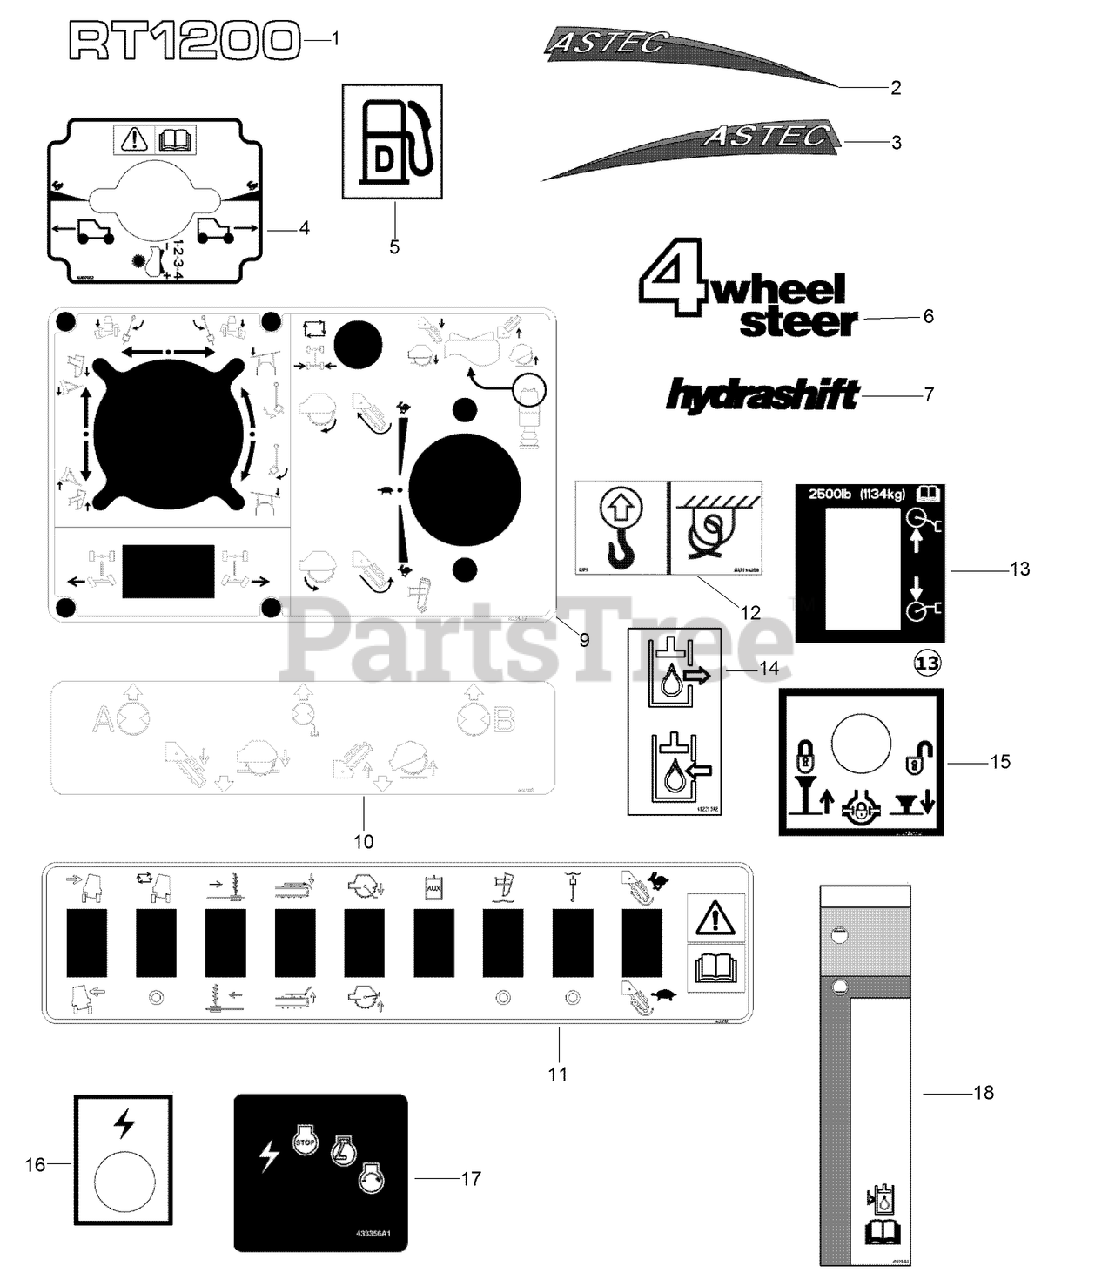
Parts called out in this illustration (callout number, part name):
1	DECAL - RT1200 Model
2	DECAL - Astec Swoosh, Right Hand
3	DECAL - Astec Swoosh, Left Hand
4	DECAL - Ground Drive Joystick
5	DECAL-Diesel Fuel
6	DECAL-4 Wheel Steering
7	DECAL - Hydrashift Model Name
9	DECAL - Op Rhs Joystick
10	DECAL - Rear Bulkhead ID
11	DECAL - Rear Switches Overlay
12	DECAL-Tie Down / Lift Hook
13	DECAL - Instrument Panel, LH
14	DECAL-Hydraulic Oil, Supply / Return
15	DECAL-Instrument Panel, RH
16	DECAL-Instrument Panel, RH
17	DECAL-Key Switch
18	DECAL-Hydraulic Oil Level
